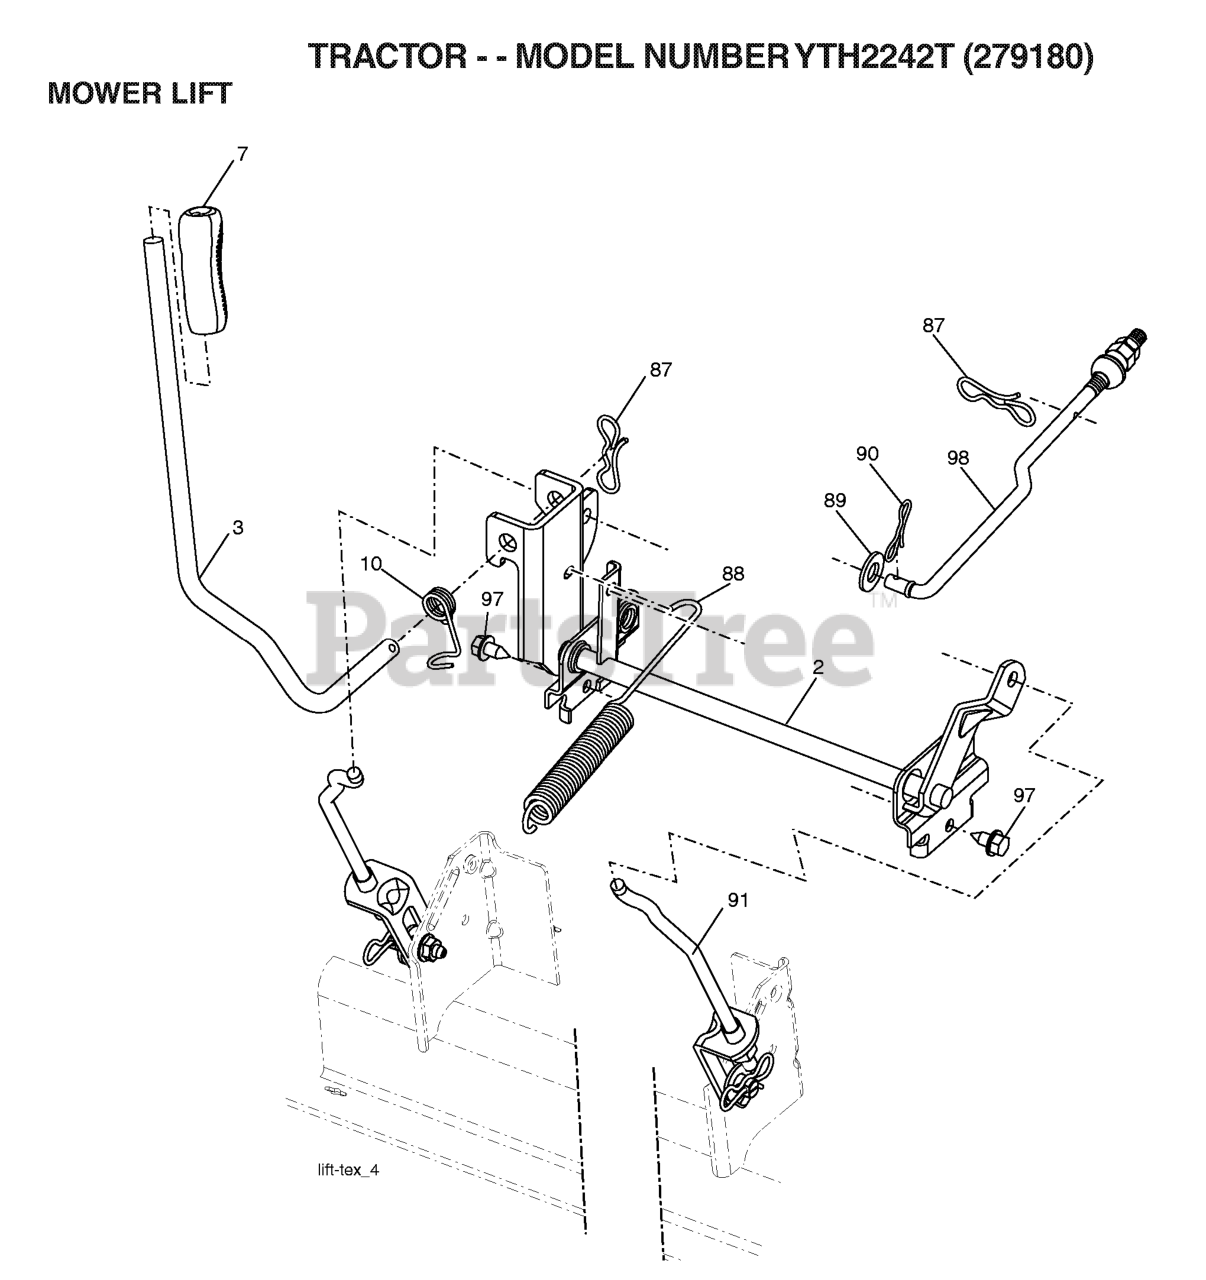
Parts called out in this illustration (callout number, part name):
2	SHAFT.ASM.LIFT.CROSS.H
3	LEVER.LIFT.HANDLE.LT
7	GRIP.LEVER.5625.ID
10	SPRING.TORSION.LIFT.HANDLE
87	PIN.COTTER.7/16.BOW TI.
88	SPRING.LIFT.ASSIST.LT
89	WASHER.CLEAR.ZINC
90	PIN.COTTER.5/16.BOW TI
91	LINK.ASM.LIFT.REAR
97	SCREW 3/8-16X3/4
98	LINK.ASM.SUSP.FRONT.MW
